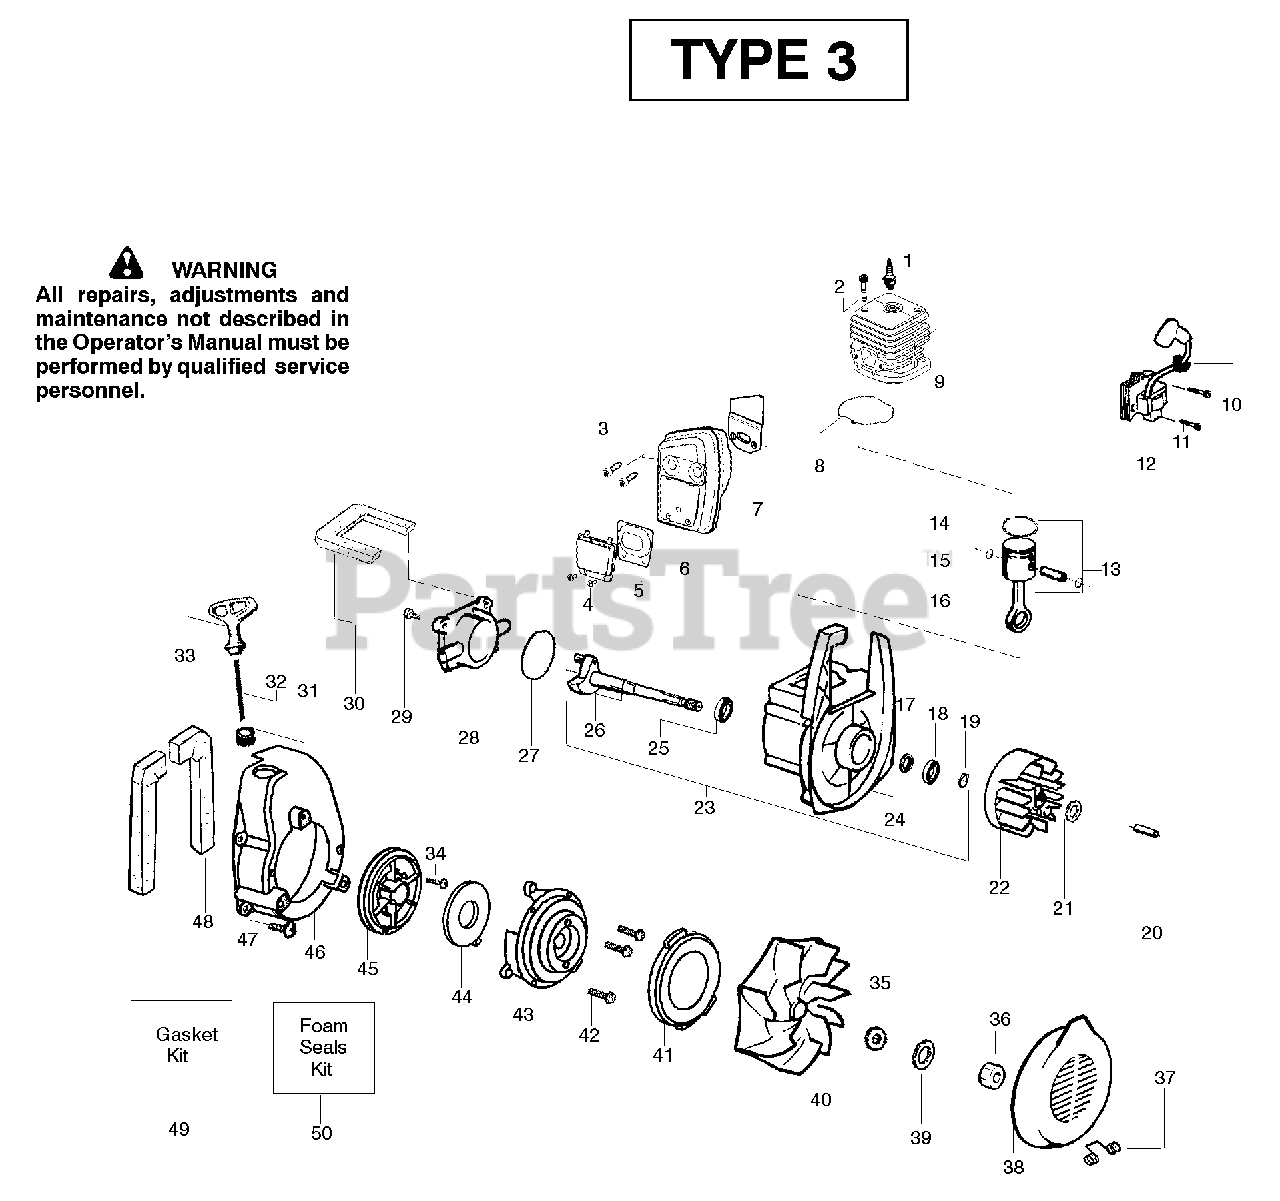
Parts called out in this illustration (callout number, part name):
1	Spark Plug (RCJ-6Y)
3	Screw-Muffler-Internal
5	Kit-Spark Screen
6	Kit-Muffler
7	Gasket-Baffle (kit)
8	Gasket-Cylinder (kit)
9	Kit-Cylinder
10	Grommet-Ign. Module
11	Screw-Ignition Module
12	Ignition Module
13	Kit-Piston
14	Piston Ring
15	Retainer-Piston Pin
16	Assy-Connecting Rod
17	Seal-Crankcase
18	Bearing-Outer
19	Retainer Ring-C’chaft
20	Spacer-Flywheel
22	Assy-Flywheel
23	Assy-Crankcase/Crank shaft
24	Assy-Crankcase
25	Bearing-Inner
26	Assy-Crankshaft
27	O-ring-C/case (kit)
28	Cover-Crankcase
29	Screw
30	Foam-219mm (kit)
31	Eyelet-Flange
32	Kit-Rope
33	Handle-Starter
35	Washer-Belleville
37	Spring-Return Cover
40	Assy-Impeller
43	Housing-Pulley
44	Spring-Starter
45	Kit-Starter Pulley
47	Screw
48	Foam-182mm (kit)
49	Kit-Gasket
50	Kit-Foam Seals
